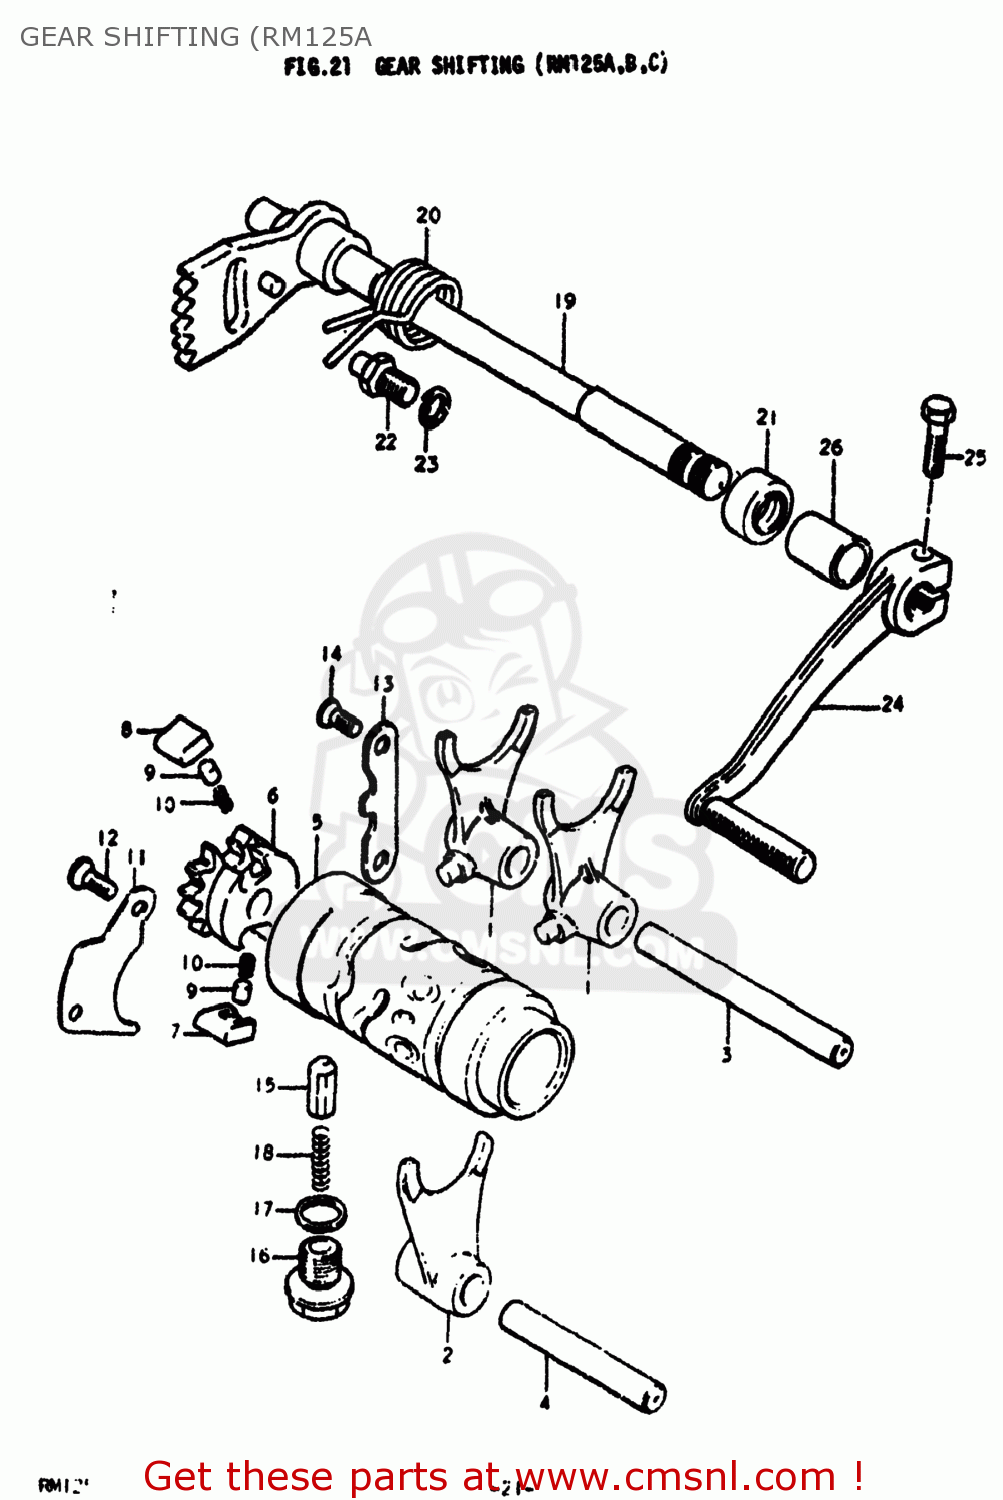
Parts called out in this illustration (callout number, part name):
1	FORK,GEAR SHIFT NO.1
2	FORK,GEAR SHIFT NO.2
3	SHAFT,GEAR SHIFT FORK
4	SHAFT,GEAR SHIFT FORK
5	CAM,GEAR SHIFT
6	RETAINER,GEAR SHIFT CAM
7	PAWL,GEAR SHIFT NO.1
8	PAWL,GEAR SHIFT NO.2
9	PIN(5X8)
10	SPRING
11	LIFTER,GEAR SHIFT PAWL
12	SCREW
13	STOPPER,GEAR SHIFT POLE
14	SCREW
15	STOPPER,GEAR SHIFTING
16	BOLT,GEAR SHAFT CAM STOPPER
17	GASKET(14X19.2X2) (NAS)
18	SPRING
19	SHAFT,GEAR SHIFT
20	SPRING
21	OIL SEAL
22	STOPPER,GEAR SHIFT CAM
23	LOCK WASHER
24	LEVER ASSEMBLY,GEAR SHIFTING
25	BOLT
26	CUSHION
